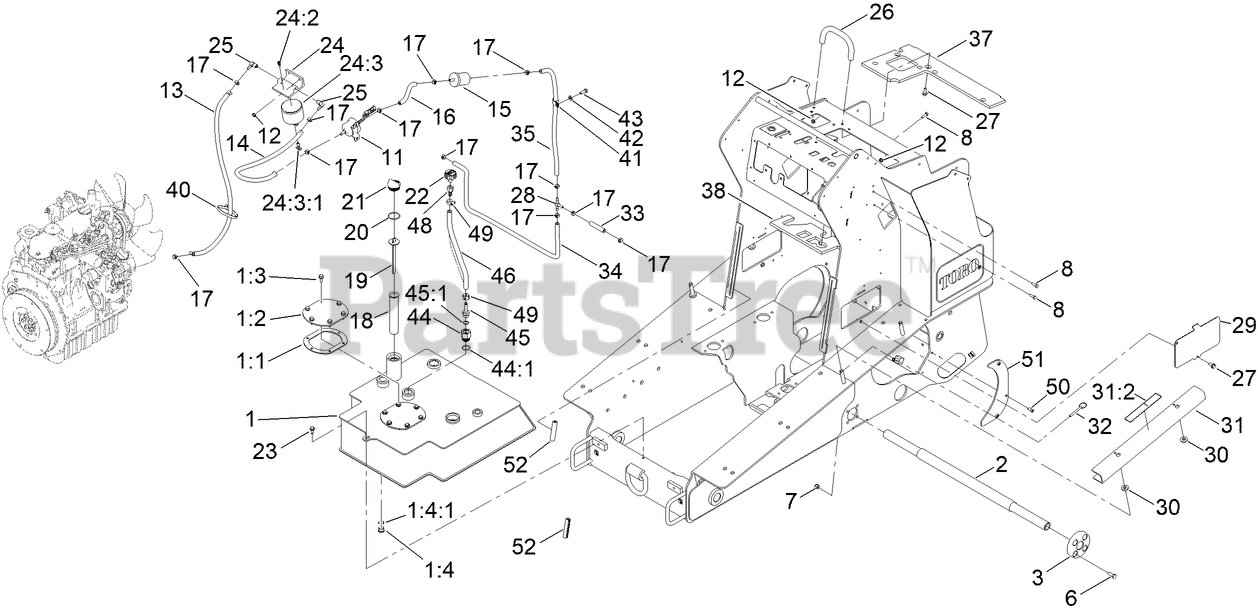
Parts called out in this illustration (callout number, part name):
1	TANK-HYD
1:1	GASKET-COVER, ACCESS
1:2	COVER-TANK
1:3	SCREW-HHF
1:4	PLUG-HEX
1:4:1	O-RING
2	SHAFT-TRACK
3	HUB-SHAFT
6	SCREW-HH
7	NUT-LOCK, NI
8	SCREW-HH
11	PUMP-FUEL, ELECTRIC
12	NUT-HF
13	HOSE-FUEL
14	HOSE-FUEL
15	FILTER-FUEL
16	HOSE-FUEL
17	CLAMP-HOSE
18	FILTER-SCREEN
19	DIPSTICK
20	O-RING
21	PLUG-PLASTIC
22	BREATHER
23	SCREW-THD ROLL, HWH
24	FILTER HEAD ASM
24:2	VENT-AIR
24:3	ELEMENT-SPIN ON
24:3:1	VALVE-DRAIN
25	FITTING-HYD, 90
26	BAR-REFERENCE
27	SCREW-HHF
28	FITTING-TEE, BARBED
29	PLATE-COVER, ACCESS
30	WASHER-NEOPRENE
31	ARM-LOCKING
31:2	DECAL-DANGER
32	PIN-COTTERLESS
33	HOSE-FUEL
34	HOSE-FUEL
35	HOSE-FUEL
37	FOAM-HEAT SHIELD
38	FOAM-HEAT SHIELD
40	TIE-CABLE
41	CLAMP-R
42	WASHER-FLAT
43	SCREW-HH
44	FITTING-STRAIGHT
44:1	O-RING
45	FITTING-STR
45:1	O-RING
48	FITTING-FEMALE, BARBED
49	CLAMP-HOSE
50	PLATE-DIRT
51	SCREW-BHTF
